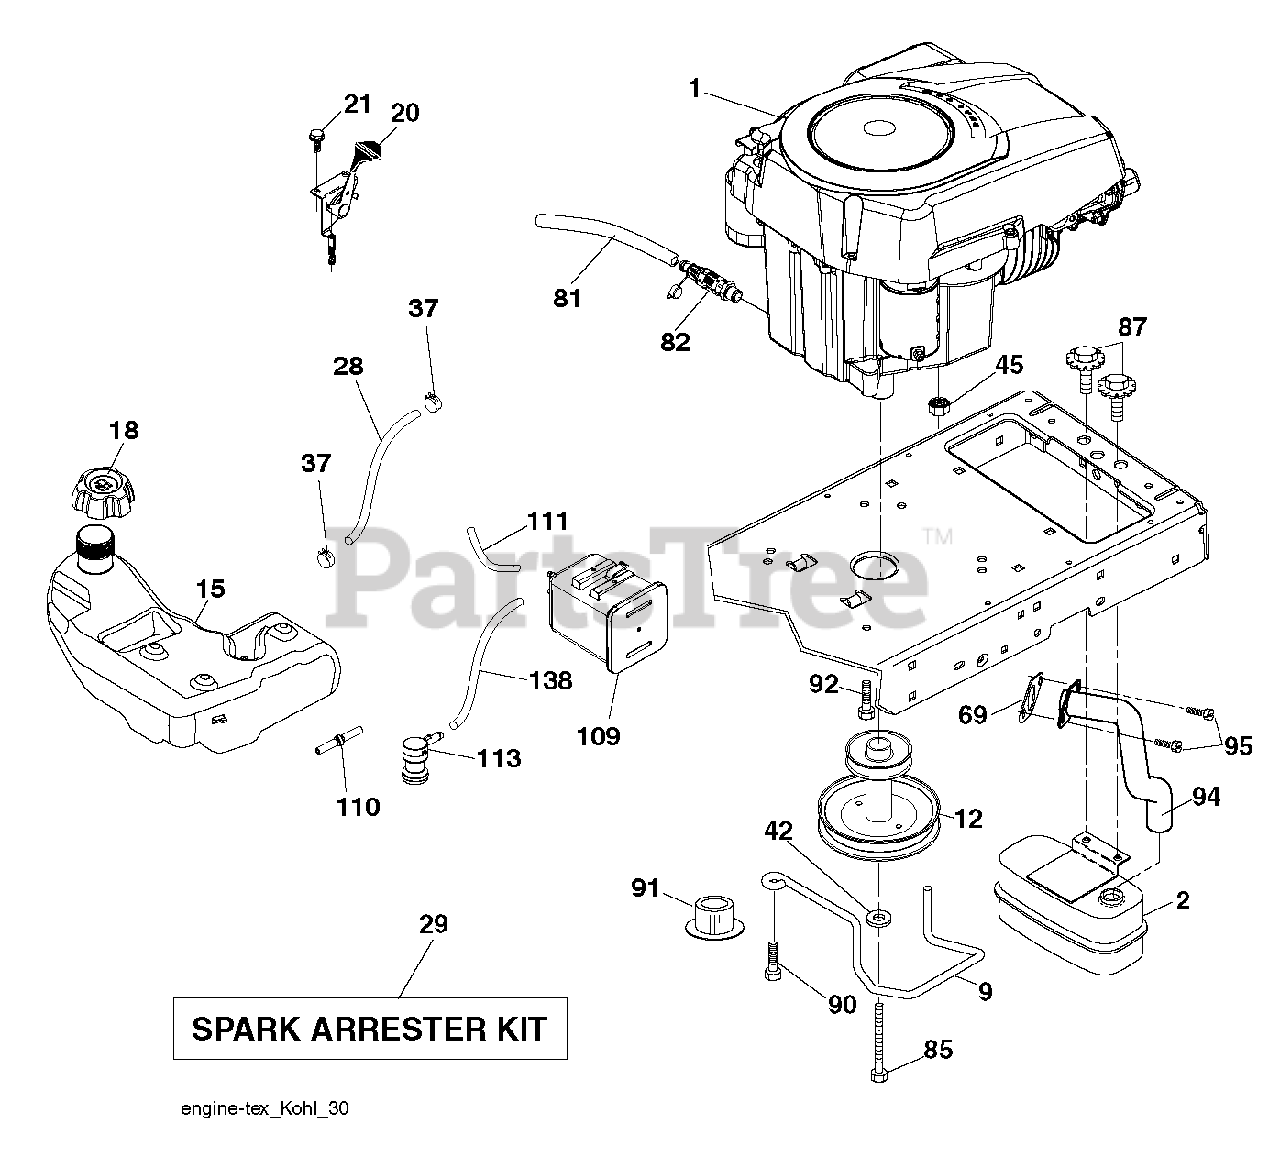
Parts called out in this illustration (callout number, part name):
2	MUFFLER.ASM.SNGL.XTNDED.DFLCTR
9	KEEPER.BELT.ENGINE.4.2
12	PULLEY ENGINE
18	CAP.ASM.FL.RITCH.3"E10.SYM.498
20	CONTROL.TH/CK.COBRA.KO
21	SCREW.#10 X 0.750.BOS
28	LINE.FUEL.64"REAR.EMIS
29	KIT.SPARK ARRESTOR 794945 B&S
37	HOSE CLAMP
42	LOCKWASHER
45	NUT
69	GASKET.EXHAUST.KOHLER
81	TUBE, DRAIN OIL ASM.
82	VALUE.OIL.DRAIN
85	BOLT HEX 7/16-20X4-1/4"
87	Bolt, 5/16-18 X 1-3/4
90	SCREW 3/8-16X1
91	BUSHING.1.375OD
92	SCREW 3/8-16X1
94	RP.TUBE.EXHAUST.KOHL.COURAGE
95	SCREW.SOCKET HD.5/16-1
109	CANNISTER, CARBON
110	VALVE.ASM.ANTI-SLOSH
111	RP PURGE LINE
113	VALVE.SLANT.CARTRDG.90 DEG.TEX
138	PURGE.LINE.36"REAR.CALIFORNIA
